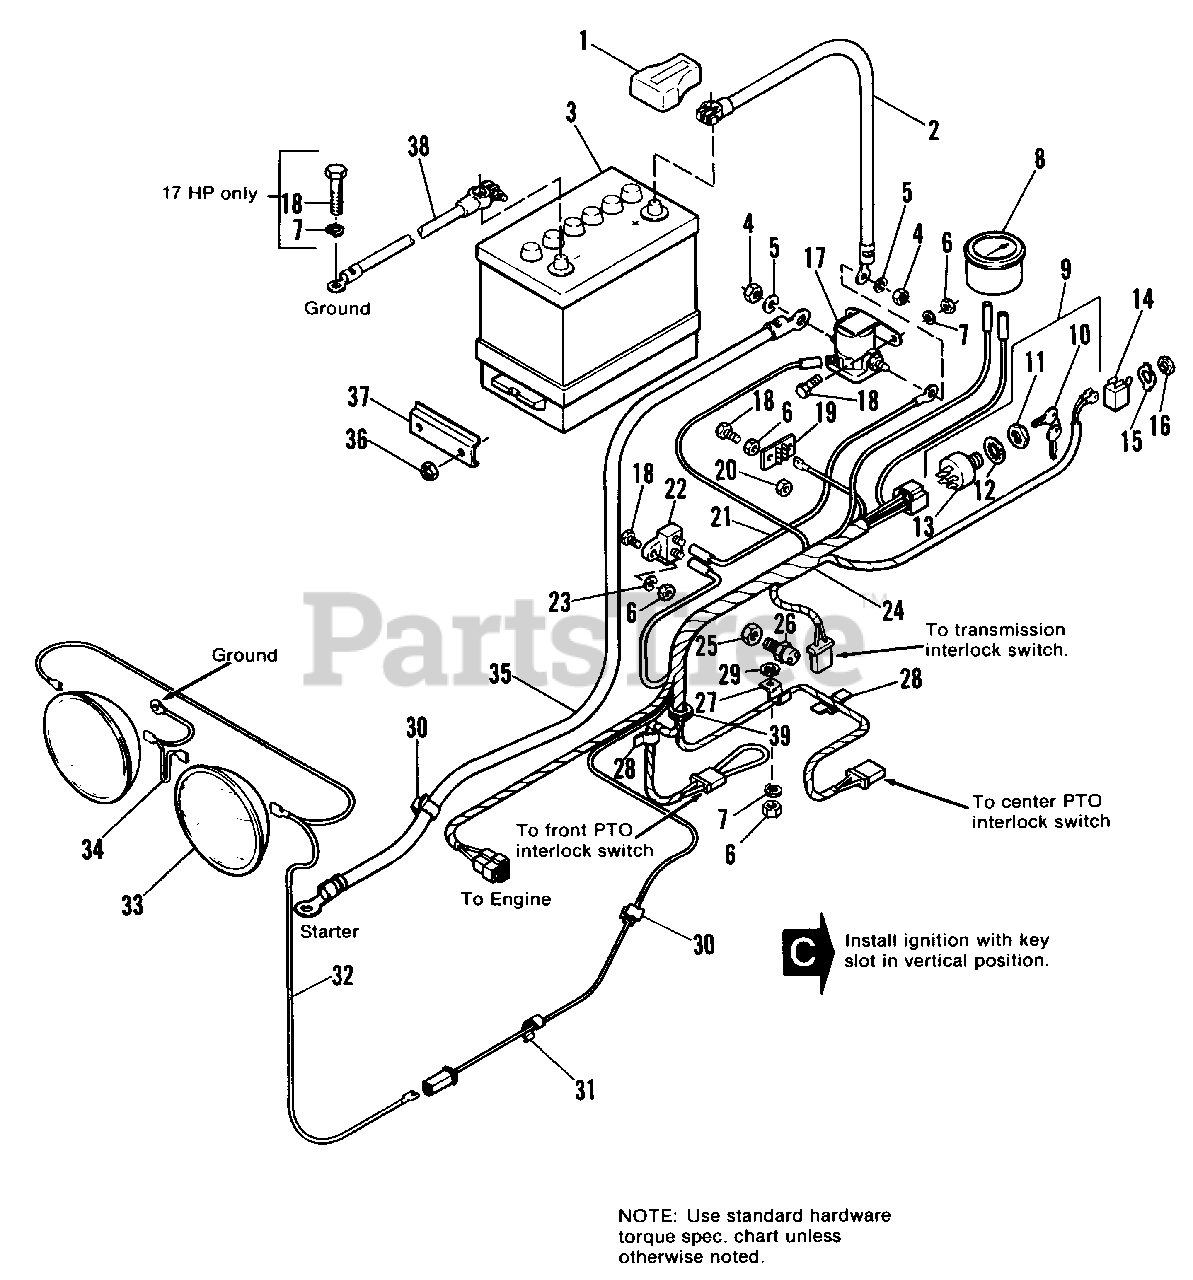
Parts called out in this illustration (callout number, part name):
1	PROTECTOR, Terminal
2	CABLE, Battery to Solenoid
3	BATTERY (Includes Decal)
4	NUT, Hex, 5/16-18
5	LOCKWASHER, 5/16
6	NUT, Hex, 1/4-20
7	LOCKWASHER, 1/4 (Qty.3 used on 7112 Only)
9	SWITCH & KEY ASSY., Ignition
11	NUT, Special
12	LOCKWASHER, Internal Tooth, 5/8
14	SWITCH, Toggle
16	NUT, Switch
17	SOLENOID, Starter
18	CAPSCREW, Hex Hd., 1/4-20 x 5/8 (Qty. 5 used on 7112 only)
19	BOARD, Terminal
20	LOCKNUT, Hex, 1/4-20
22	CIRCUIT BREAKER
23	LOCKWASHER, 1/4
24	HARNESS ASSY.
25	NUT, Pal
26	SWITCH, Interlock
27	CLIP, Cable
28	CLIP, Wire
29	WASHER, Cup
30	CLIP, Tinnerman
31	CLIP, Tinnerman
34	WIRE ASSY.
35	CABLE, Solenoid to Starter
36	NUT, Elastic, 5/16-18
38	CABLE, Battery to Ground
